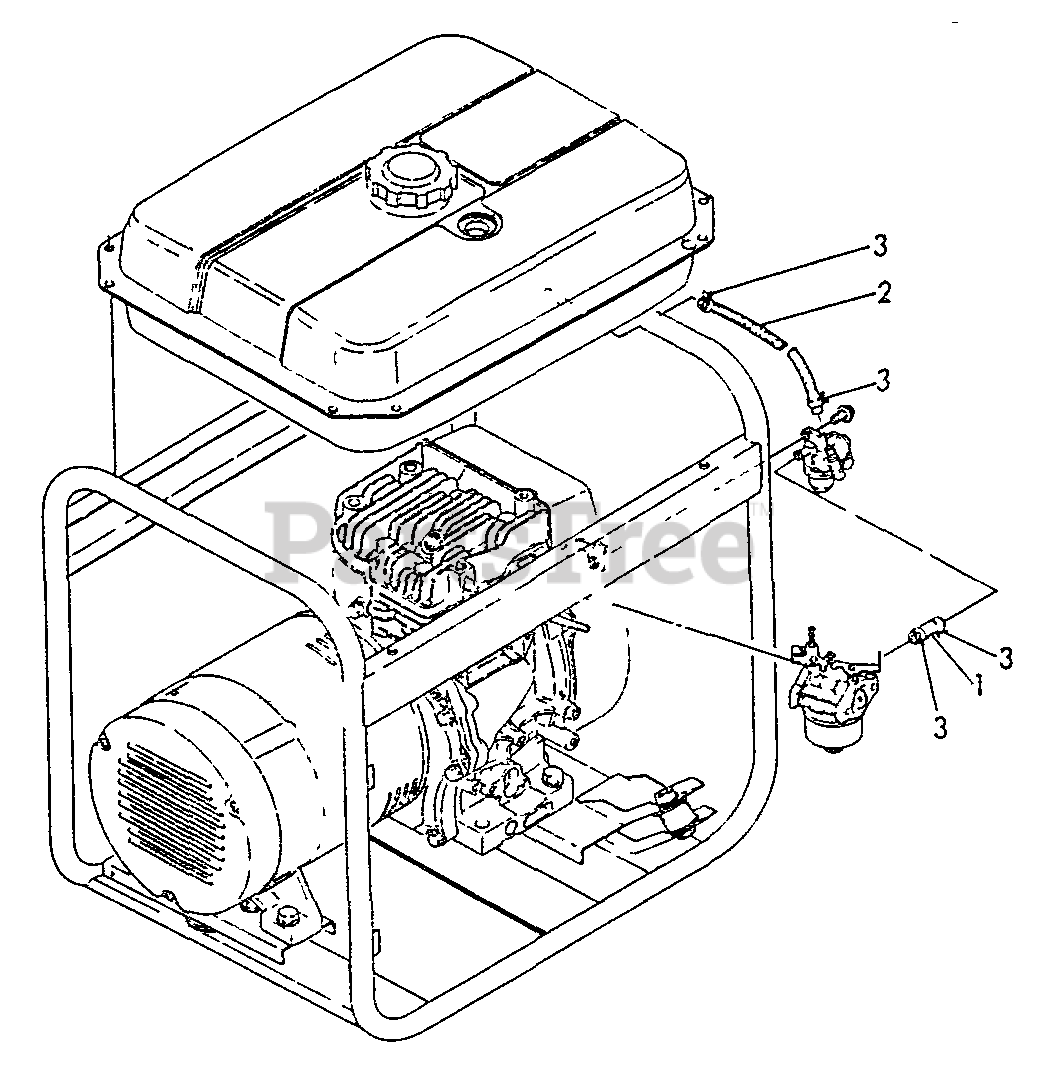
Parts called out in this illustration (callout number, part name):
1	PIPE - FUEL
2	PIPE - FUEL
3	CLAMP
